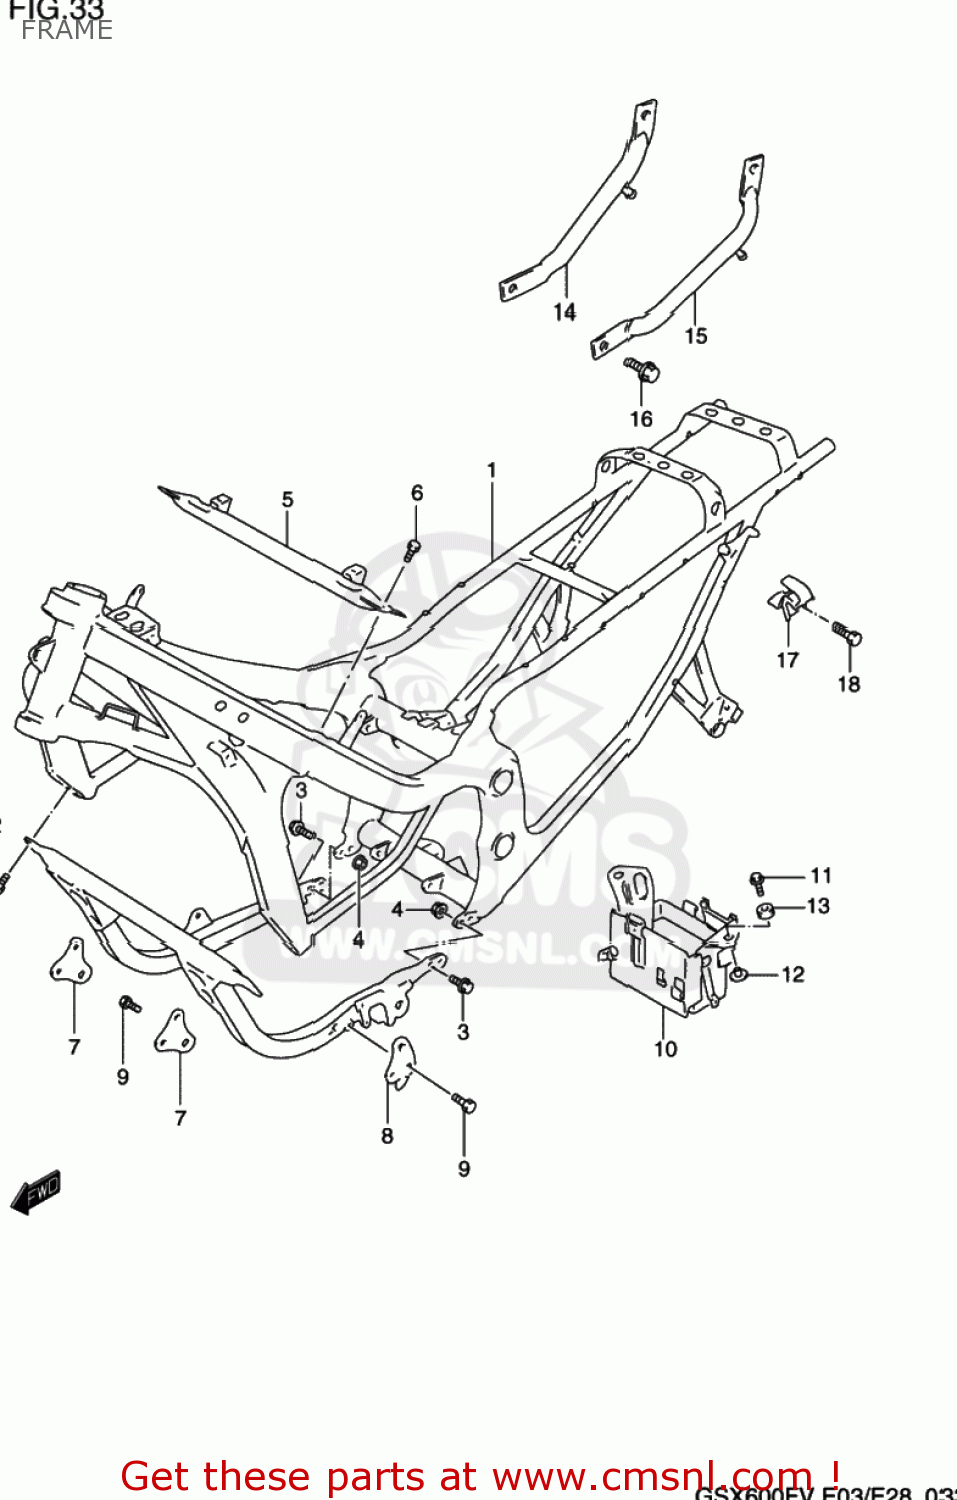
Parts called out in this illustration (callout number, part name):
1	FRAME SET(BLACK)
2	BOLT
3	BOLT
4	NUT
5	TUBE,FRAME BRIDGE NO.2
6	BOLT(8X20)
7	PLATE,ENG MTG NO.1
8	PLATE,ENG MTG NO.2,L
9	BOLT, UPPER
10	HOLDER,BATTERY
11	BOLT
12	WASHER
13	CUSHION
14	GRIP,REAR,RIGHT
15	GRIP,RR,L
16	BOLT
17	HOLDER,HELMET
18	BOLT
